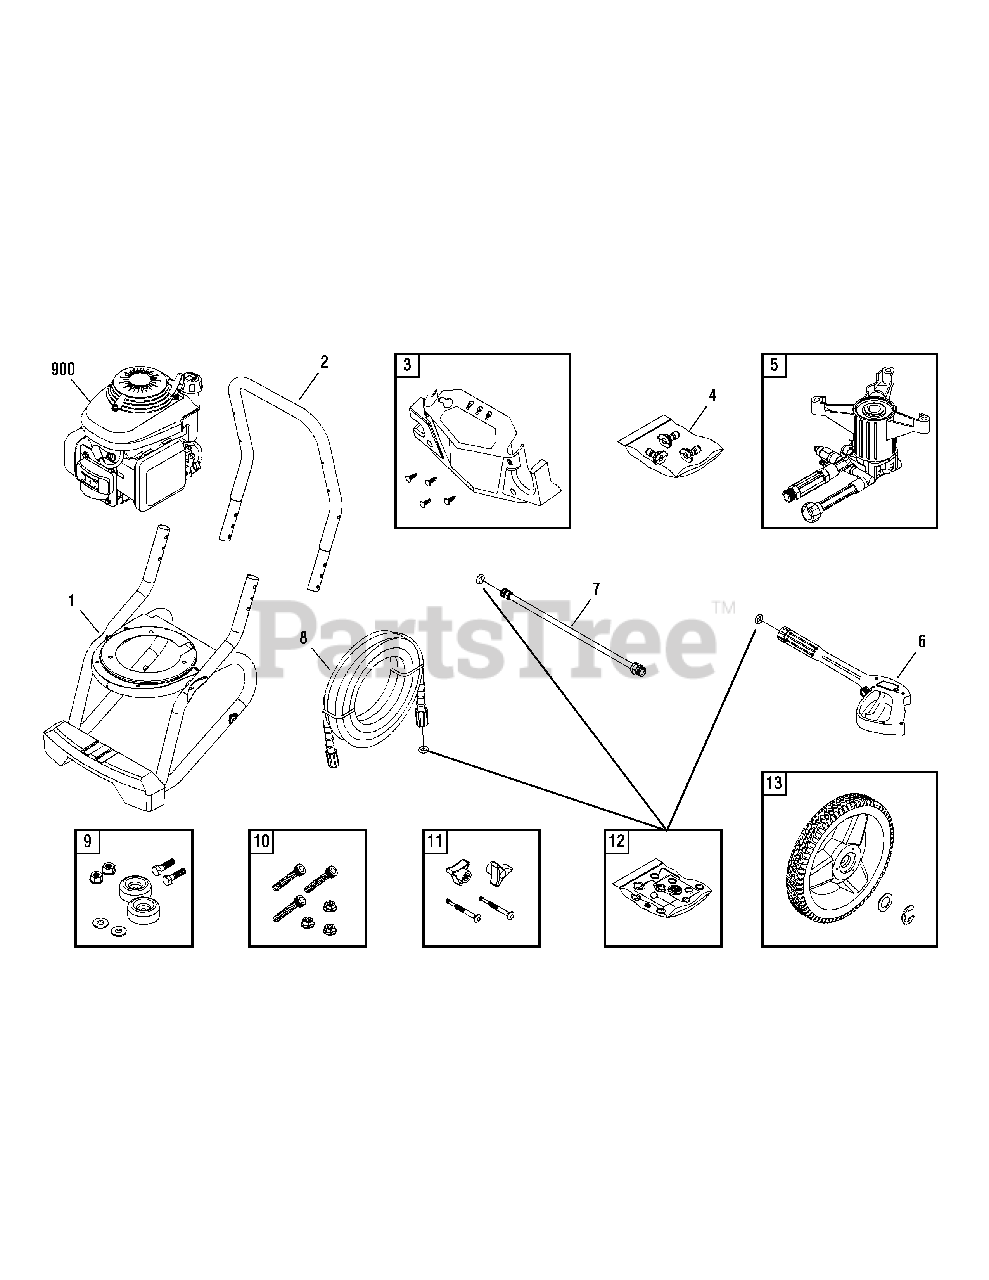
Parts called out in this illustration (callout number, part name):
4	KIT, QC Nozzles
5	PUMP
6	GUN
7	EXTENSION, QC
8	HOSE
9	MOUNT, Vibration
10	KIT, Hardware, Pump Mounting
11	KIT, Hardware, Handle
12	KIT, O-Ring
900	* ENGINE
